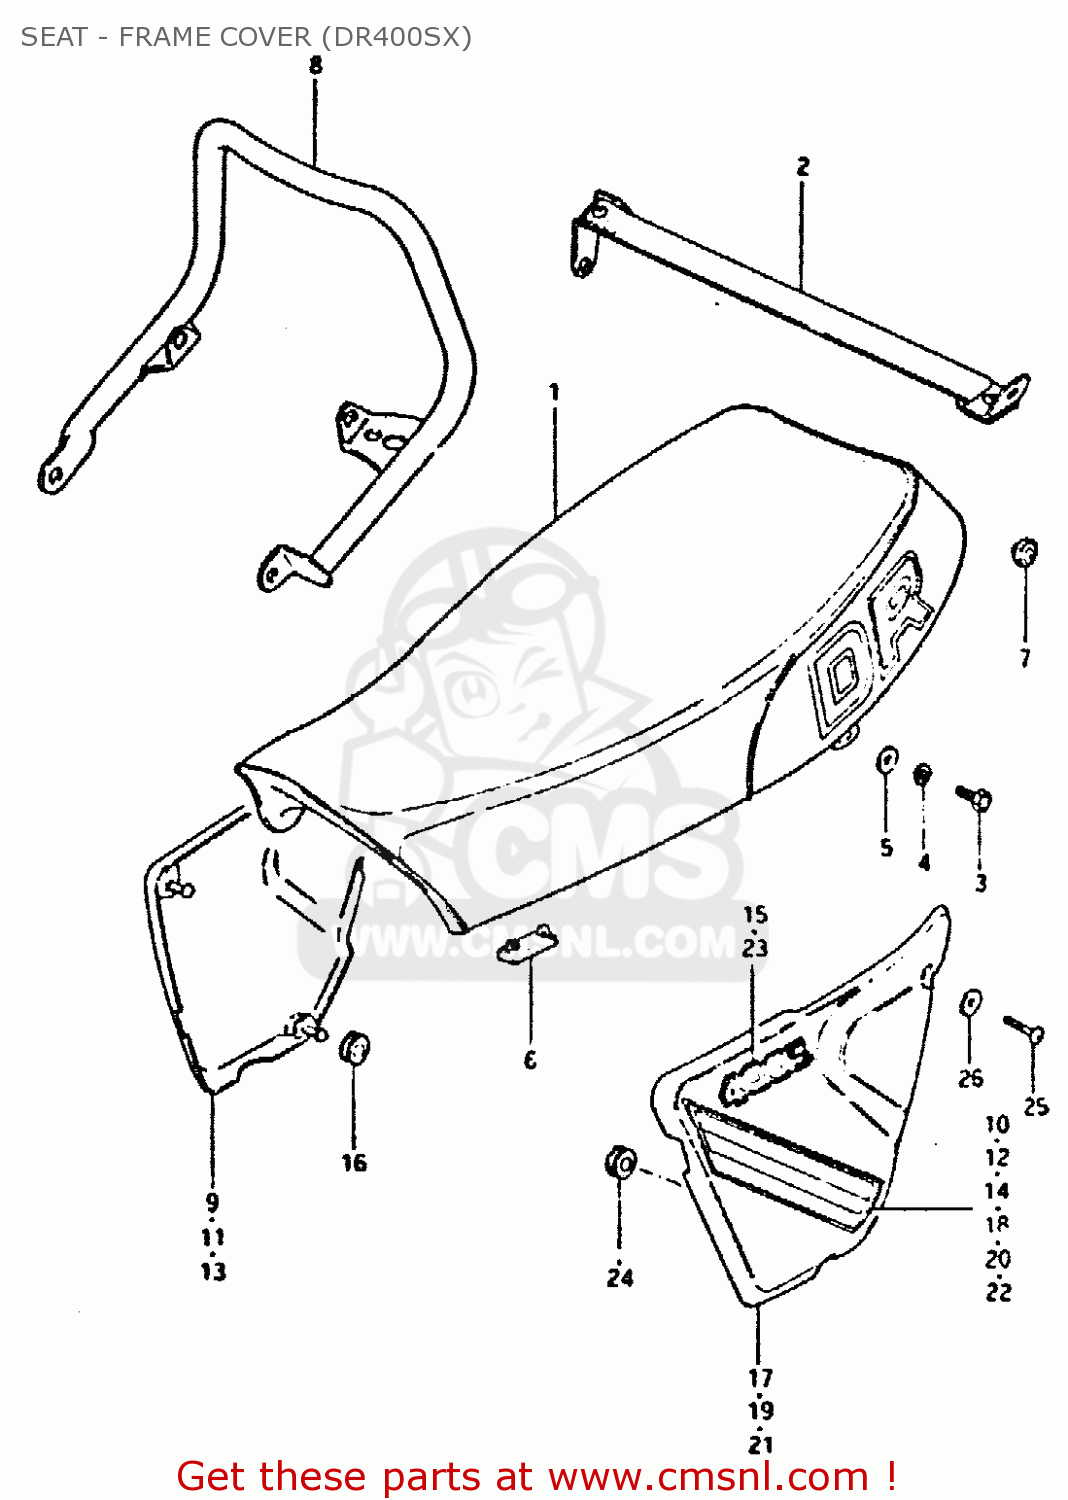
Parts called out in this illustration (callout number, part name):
1	SEAT ASSY (BLACK)
2	BAND, SEAT GRIP
3	BOLT
4	LOCK WASHER
5	WASHER
6	CUSHION
7	CUSHION
9	COVER,FRAME,RIGHT
10	TAPE, RH
11	COVER, FRAME RH (BLUE)
12	TAPE, RH
13	COVER, FRAME RH (RED)
14	TAPE, RH
15	EMBLEM
16	CUSHION
17	COVER,FRAME,LEFT
18	TAPE, LH
19	COVER, FRAME LH (BLUE)
20	TAPE, LH
21	COVER, FRAME LH (RED)
22	TAPE, LH
23	EMBLEM
24	CUSHION
25	SCREW
26	WASHER
